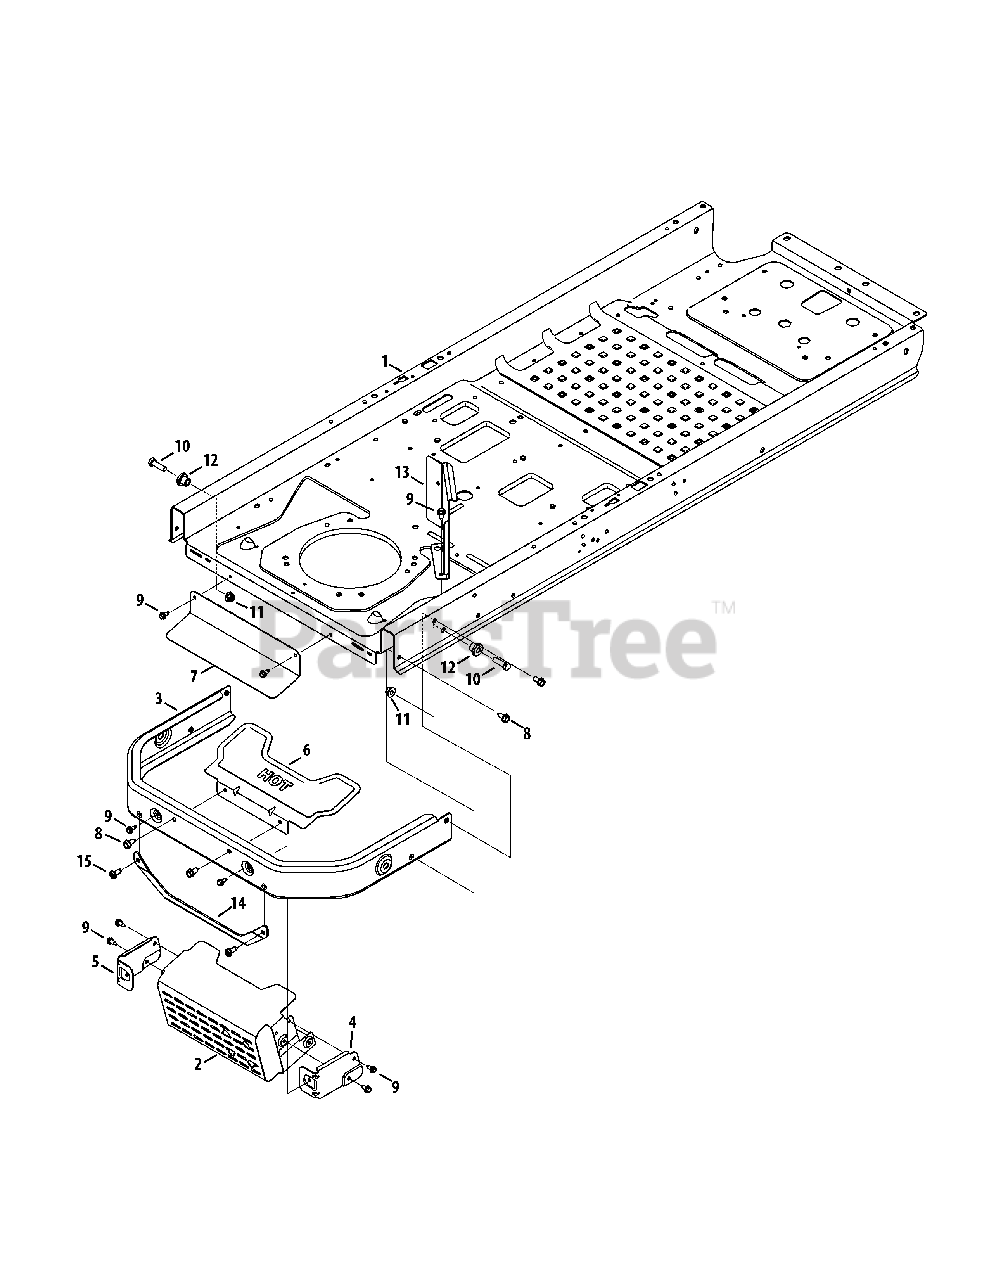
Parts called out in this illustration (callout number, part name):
1	Frame Assembly
2	Muffler Shield Assembly
4	Muffler Mounting Shield Bracket, RH
5	Muffler Mounting Shield Bracket, LH
6	Muffler Shield
7	Lower Heat Shield
8	Hex Washer Screw, 5/16-18 x .750
9	Hex Washer Screw, 1/4-20 x .625
10	Hex Screw, 3/8-16 x 1.25
11	Flange Lock Nut, 3/8-16
12	Shoulder Spacer, .38 x 1.0 x .70
13	Engine Heat Shield
14	Rear Muffler Shield Bracket
15	Screw, Self-Tapping, 5/16-18, 0.750
